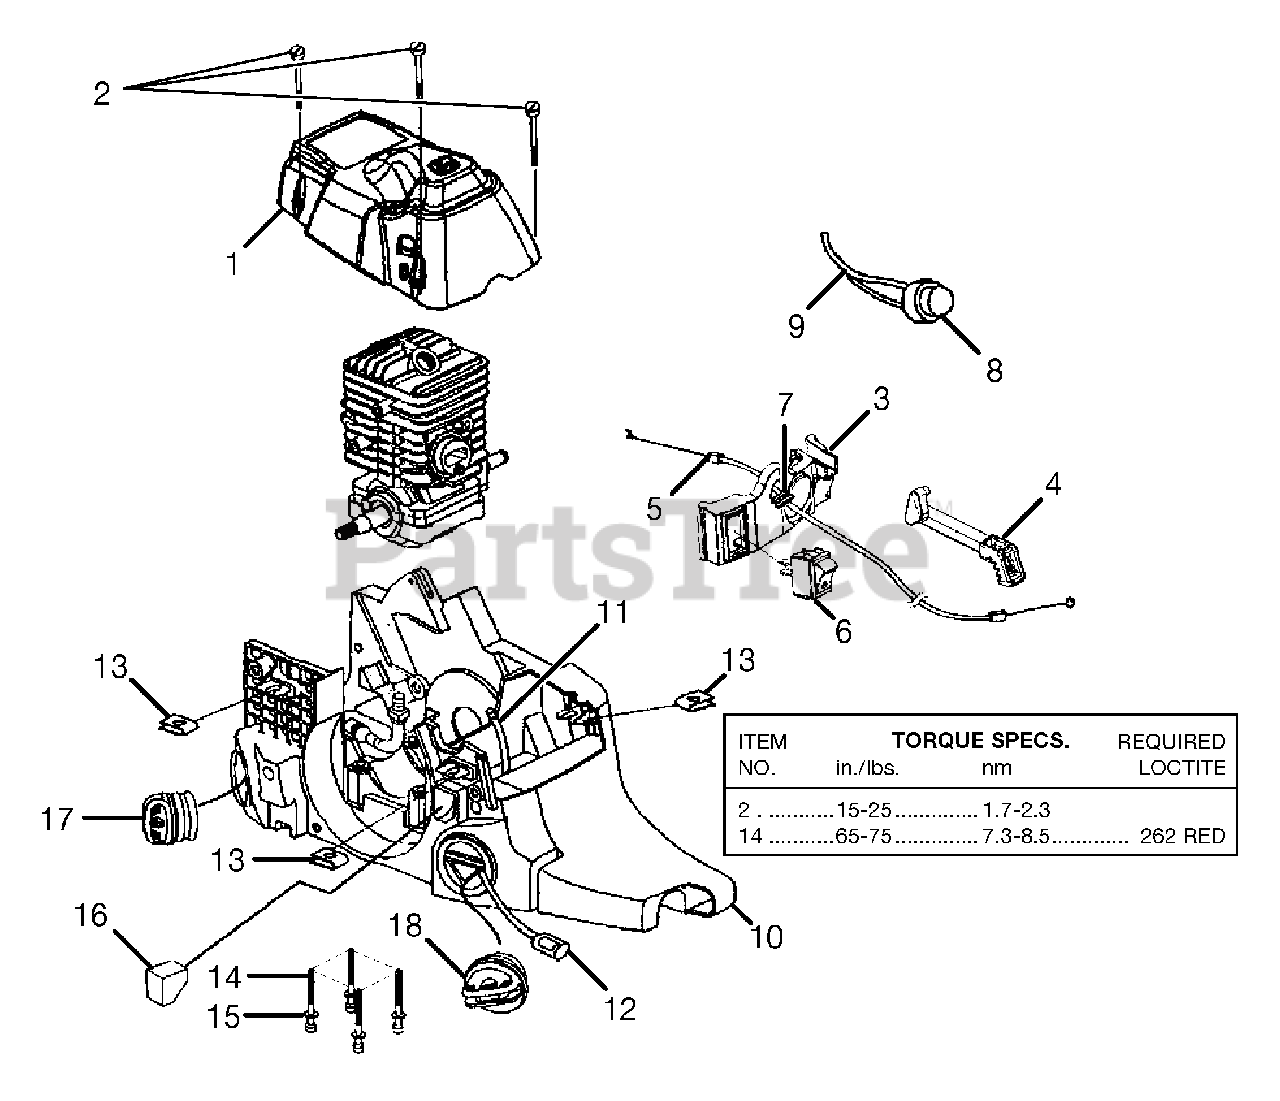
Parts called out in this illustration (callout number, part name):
1	CYLINDER COVER
2	SCREW (10-16 X 1.5 PAN HD.)
3	CONTROL PANEL
4	ROD, CHOKE
5	THROTTLE CABLE
6	SWITCH, ROCKER
7	GROMMET - SPLIT
8	PRIMER BULB
9	RUBBER TUBING (5-1/2 in.)
10	CHASSIS ASSEMBLY (45CC)
11	RUBBER TUBING (8-1/2 in.)
12	FUEL FILTER
13	SPEED NUT
14	SCREW (10-24 x 2 in.)
15	WASHER
16	PRE FILTER
17	OIL CAP
18	FUEL CAP
